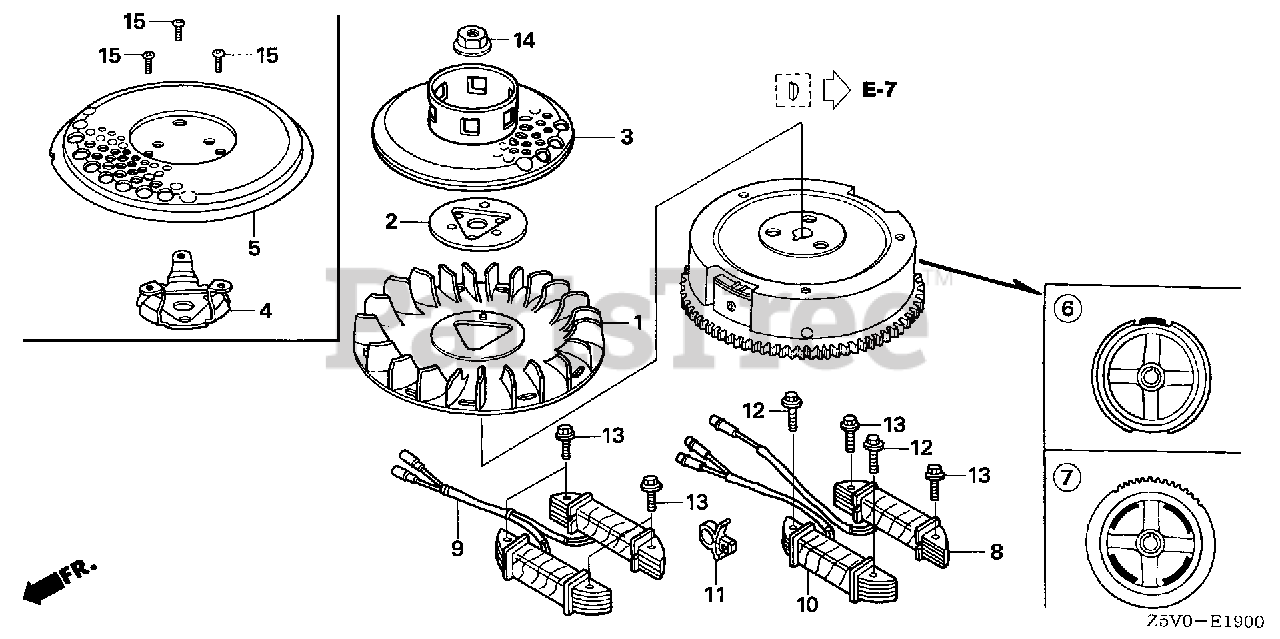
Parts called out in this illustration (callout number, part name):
1	FAN, COOLING
3	PULLEY, STARTER (SCREEN GRID)
6	FLYWHEEL
14	NUT, SPECIAL (16MM) (1)
14	NUT, SPECIAL (16MM)
